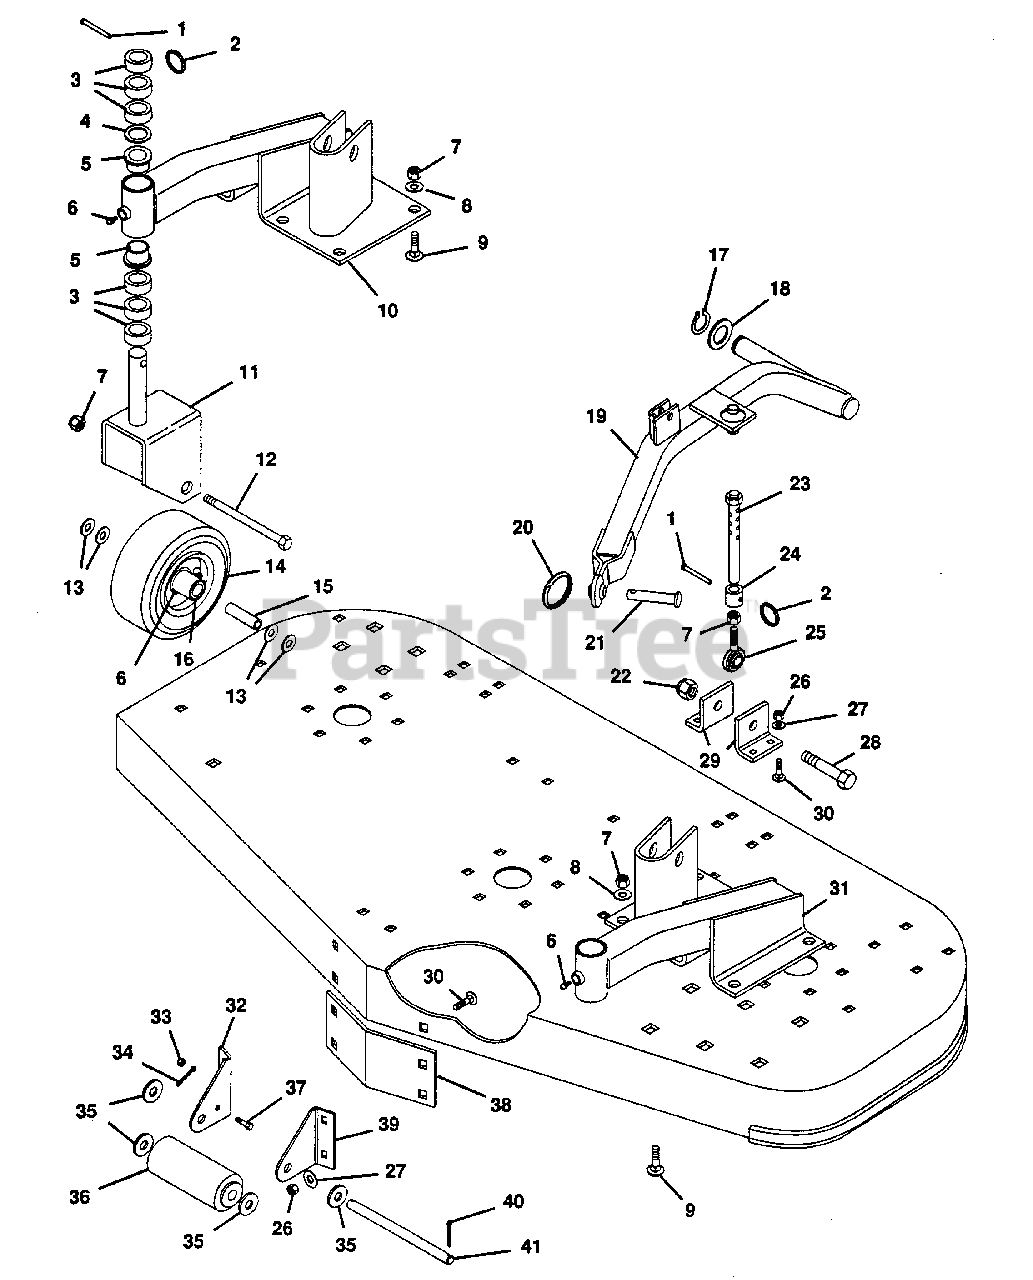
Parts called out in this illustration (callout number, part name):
1	Pin, Clevis .31x2.25
2	Ring, Split 1.25
3	Bush., St. 1.07x1.75x.50 Stl.
4	Race, Bearing Thrust
5	Bush., Flg. 1.03x1.75x.750 Ny.
6	Fitting, Lube 1/4-28
7	Nut, Lock 1/2-13
8	Washer, Flat .531x1.062x.095
9	Bolt, 1/2-13x1.50 Rd Hd Sq Nk
10	Weldment, Wheel Mounting R.H.
11	Weldment, Caster Fork
12	Bolt, Hex 1/2-13x5.50
13	Washer, Flat .531x1.250x.100
14	Wheel, Gauge
15	Bush., St. .506x.748x3.34 Stl.
16	Bearing, Gauge Wheel
17	Ring, Retaining
18	Bearing, Thrust Race
19	Weldment, Mower Arm L.H.
19	Weldment, Mower Arm R.H.
20	Ring, Split 2.24
21	Pin, Clevis .87x2.40
22	Nut, Lock 3/4-10
23	Weldment, Height Adjustment
24	Bush., St. .765x1.25x.910 Stl.
25	Rod, End
26	Nut, Lock 3/8-16
27	Washer, Flat .406x.812x.065
28	Bolt, Hex 3/4-10x3.5
29	Bracket, Deck Support Rear
30	Bolt, 3/8-16x1.00 Rd Hd Sq Nk
31	Weldment, Wheel Mounting L.H.
32	Bracket, Roller R.H.
33	Nut, Lock 1/4-20
34	Pin, Cotter .250x2.00
35	Washer, Flat .656x1.312x.095
36	Roller, Gauge
37	Bolt, Hex 1/4-20x.75
38	Plate, Deck Reinforcement
39	Bracket, Roller L.H.
40	Pin, Cotter .25x1.00
41	Shaft, Center Roller
